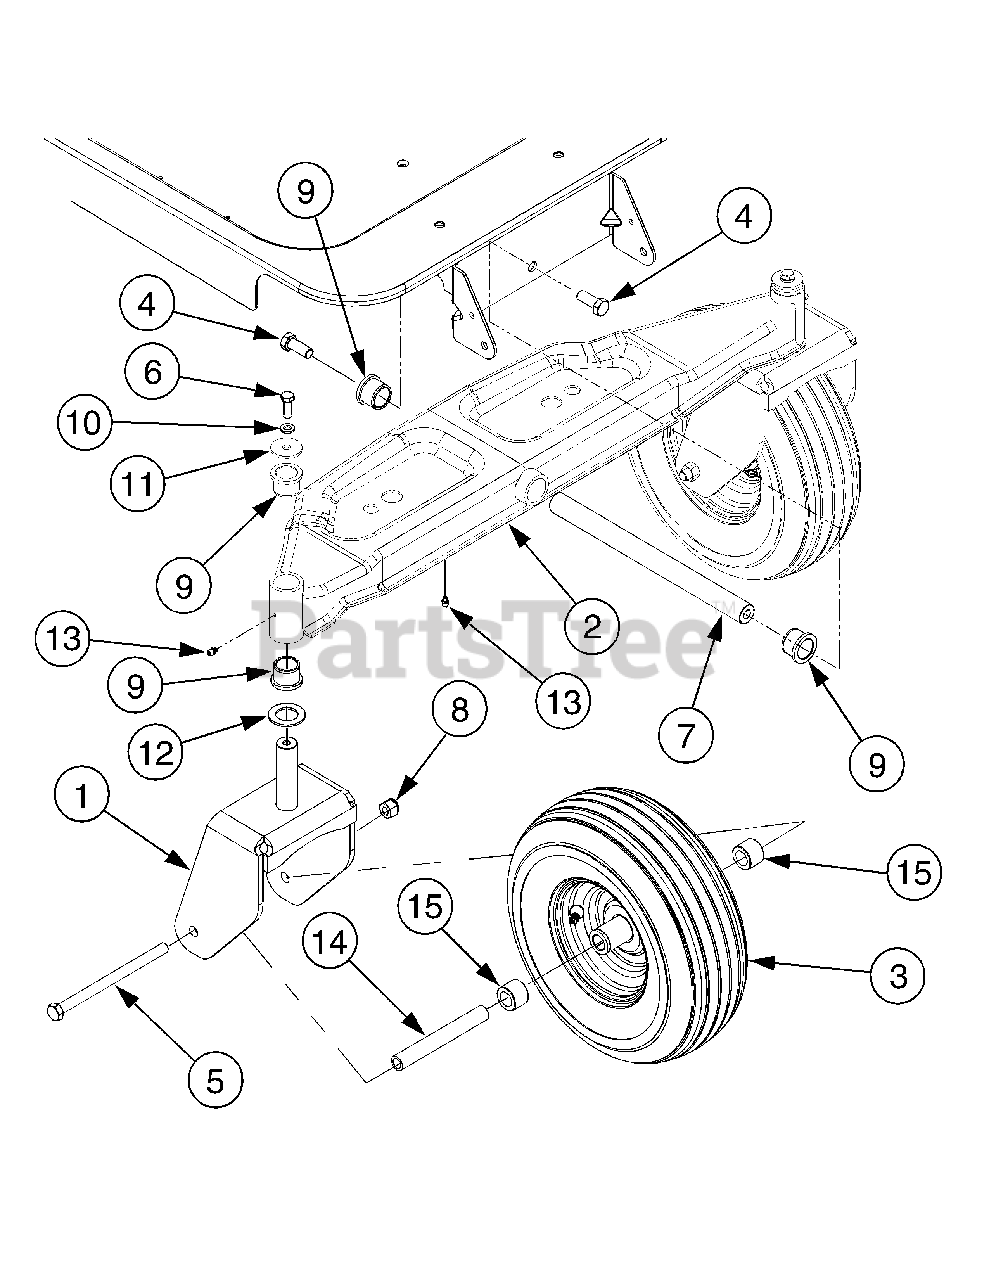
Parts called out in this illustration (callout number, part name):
4	Hex Lock Screw 1/2-13 x 1.25 Gr. 5
5	Hex Cap Screw 1/2-20 x 7.25 Gr. 5
6	Hex Screw 3/16 x 1.00
7	Axle Shaft
8	Hex In sert Lock Nut 1/2-13 Gr.B
9	Flange Bearing 1.0 x 1,246
10	L-Wash 3/8 ID
11	Flat Washer .39 ID x 1.5 OD x .135
12	Flat Washer
13	Grease Fitting
14	Spacer .51 x .75 x 5.825
15	Hub .76 x 1.23 x .92
